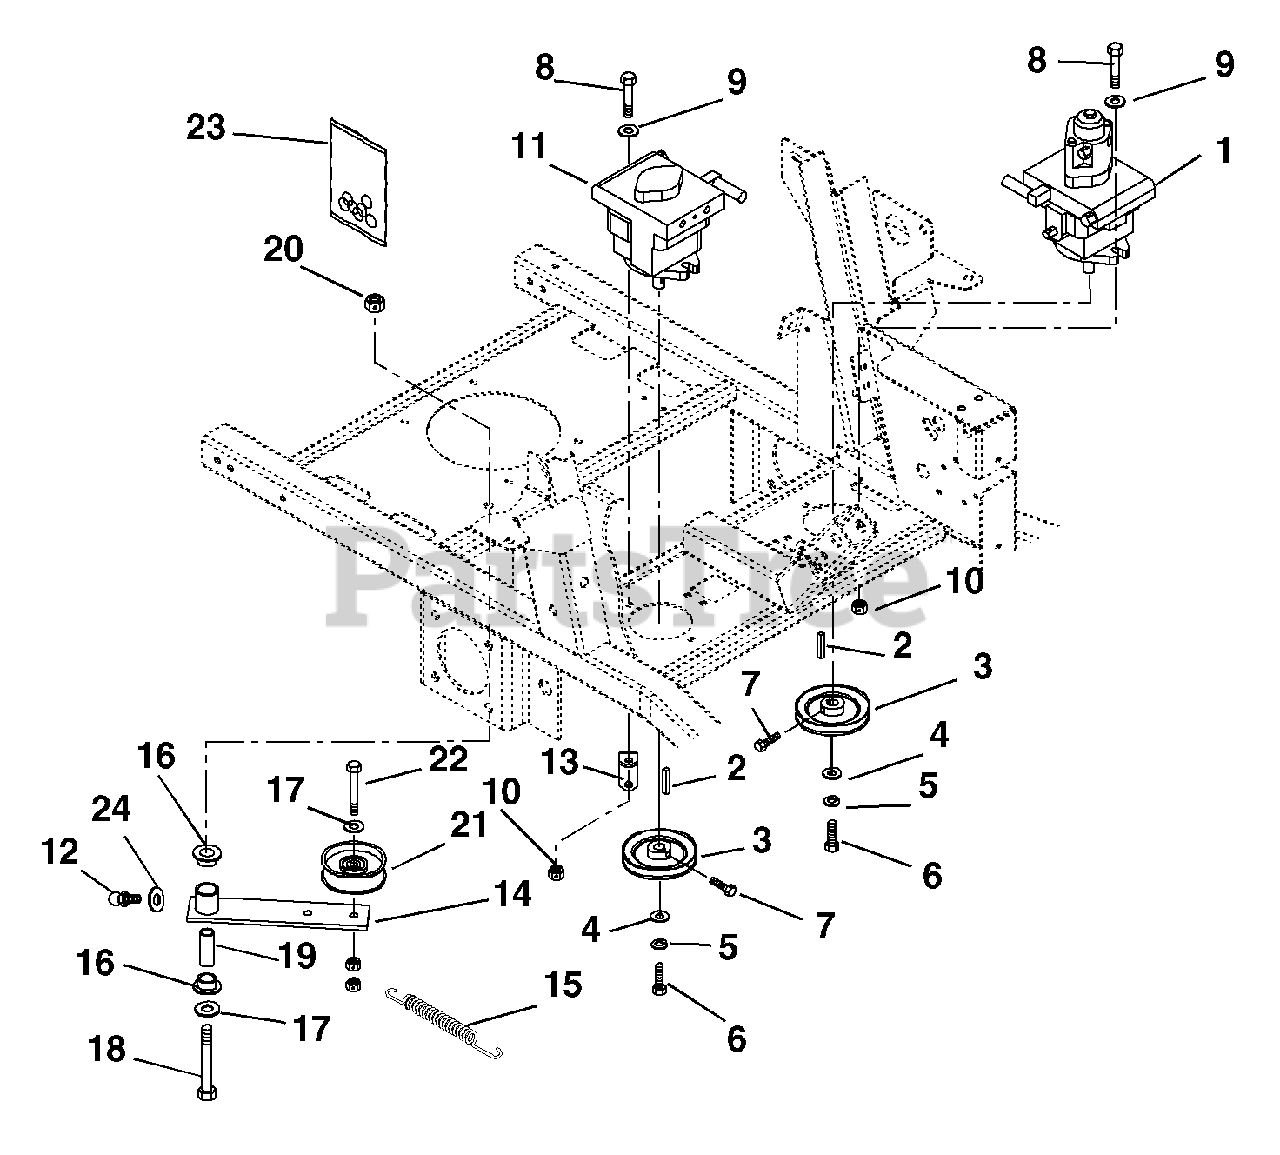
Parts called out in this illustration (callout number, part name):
1	Hydrostat BDP with Auxiliary
2	Key-Straight 5mm x 25mm x 5mm
3	Sheave 4.0 x .199
4	Washer-Flat-Steel .25 x 1.0 x .048
5	Washer-Locking .25 x .062
6	Bolt-Hex M6 x 1.0 x 12
7	Bolt-Hex .25-20 x .50 Grade 5
8	Bolt-Hex .38-16 x 1.25 Grade 5
9	Washer-Flat-Steel .390 x .75 x .125
10	Nut-Locking-Center .38-16
11	Variable-Displace Pump
12	Fitting-Lube .25-28 x .256
13	Anchor-Spring-Idler
14	Arm-Ground Drive Idler
15	Spring-Tension .120 x .845 x 6.500
16	Bushing-Flange .762 x 1.0 x .580 x 1.48
17	Washer-Flat-Steel .531 x 1.06 x .095
18	Bolt-Hex .50-13 x 3.00 Grade 5
19	Bushing-Steel .560 x .745 x 2.04
20	Nut-Locking-Center .50-13
21	Assembly-Idler Pulley
22	Bolt-Hex .38-16 x 2.25 Grade 5
23	Kit-Pump Seal
24	Washer-Flat-Steel .265 x .50 x .087
